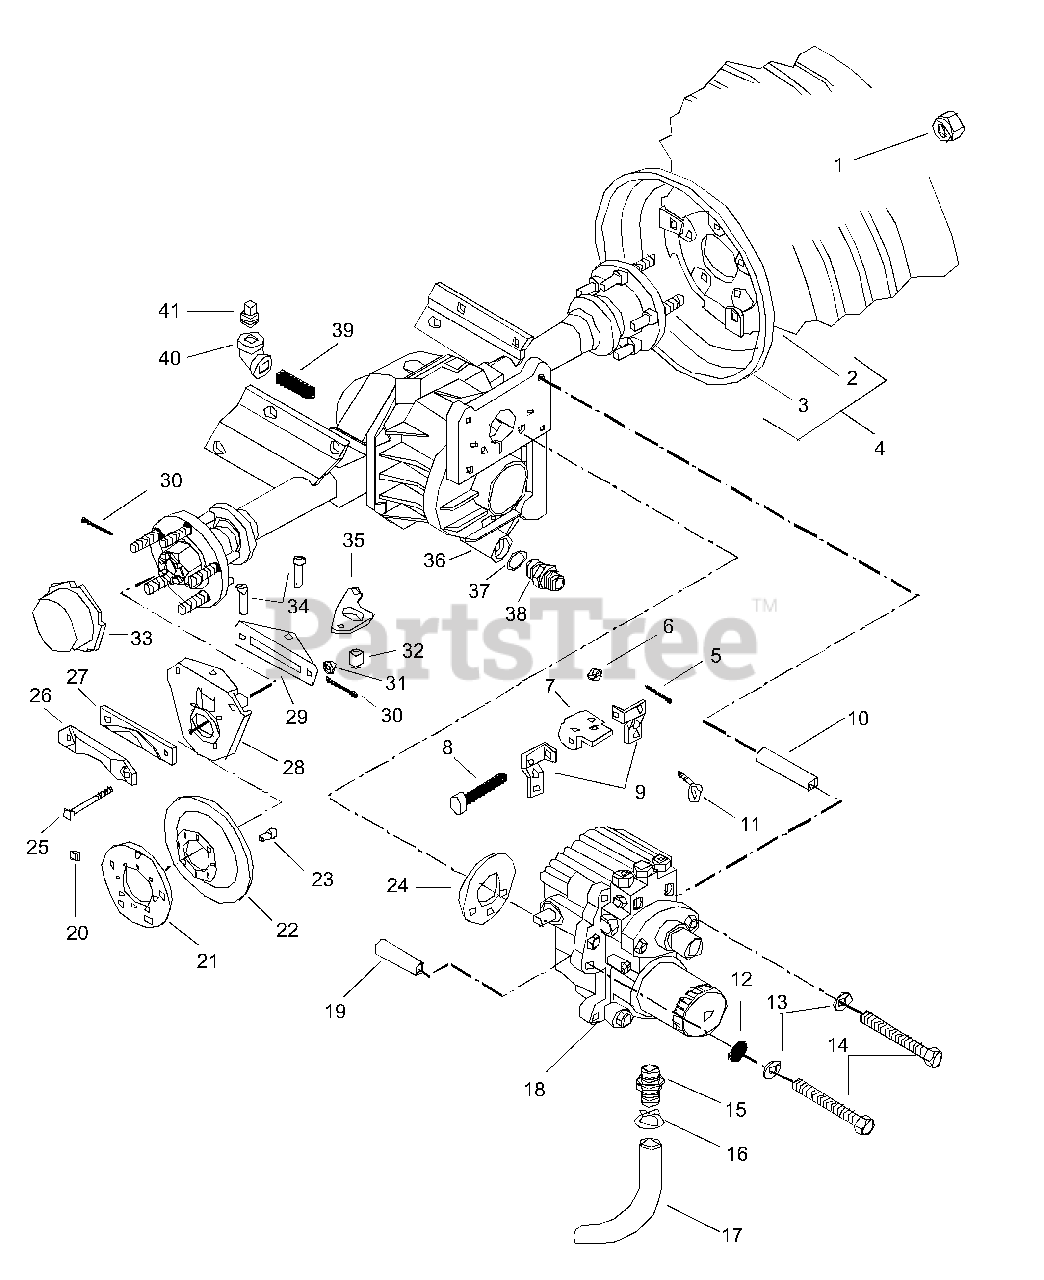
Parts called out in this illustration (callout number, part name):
1	Nut-Lug .437-20
2	Tire 23 x 10.50-12
3	Wheel
4	Tire/Wheel Assembly 10.50 x 23 Rear
5	Pin-Cotter .09 x .50
6	Nut-Locking-Flange .250-20
7	Cam
8	Clevis Pin .306/.311 x 2 1/2
9	Support
10	Spacer .379 x .625 x 3.480
11	Cable Support
12	Washer-Flat-Steel .390 x .750 x .125
13	Washer-Lock .38 x .094
14	Bolt-Hex .38-1 x 5.00 Grade 5
15	Fitting-Adapter 88-14
16	Hose Clamp #15 .906/.968
17	Hose .62 x .91 x 8.00
18	Transmission Assembly
19	Spacer .379 x .625 x 3.220
20	Grommet .125 x .375
21	Carrier
22	Disc
23	Screw-Tapping .250-20 x .37
24	Gasket
25	Bolt-Round Head Square Neck .38-16 x 3.50 Grade 5
26	Caliper Plate
27	Friction Plate
28	Caliper Mounting Plate
29	Pressure Plate
30	Pin-Cotter .09 x .75
31	Nut-Locking-Center .38-16
32	Roller
33	Rear Hub Cap
34	Clevis Pin .368/.373 x 1 5/8
35	Brake Arm
36	Rear Axle & Supports
37	O-Ring .924 x 1.156 x .116
38	Connector
39	Pipe Nipple
40	Elbow 1/2 x 90
41	Pipe Plug
